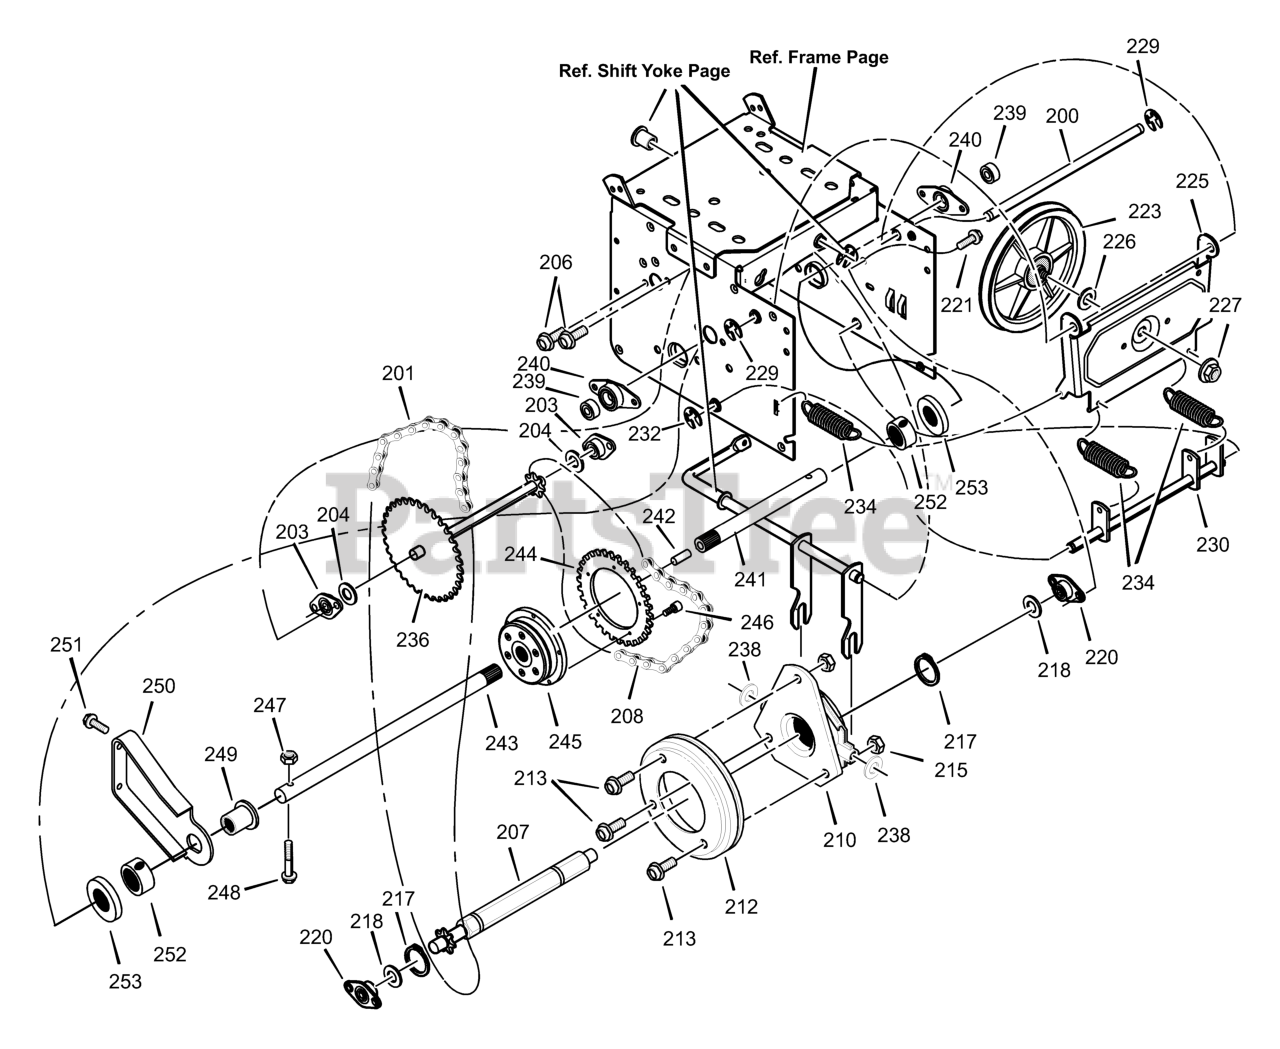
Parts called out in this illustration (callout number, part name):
200	LF AXLE, SWING PLATE YZ
201	CHAIN, ROLLER #420x19.00
203	BEARING AND RETAINER, ASSY
206	SCREW, TAP 5/16-18 x 0.5
207	ASSY, HEX SHAFT
208	CHAIN, ROLLER #420x18.00 LG
210	BEARING, TRUNION CLUTCH R
212	WHEEL, FRICTION DISC
215	NUT, KEPS HEX 1/4-20
217	RING, RETEXT
220	BEARING AND RETAINER, ASSY
221	SCREW, TAP 5/16-18 x .5
223	FRICTION PULLY
225	LF PLATE, SWINGING YZ
226	SPACER, FRICTION PULLEY
227	NUT, FLANGE LOCK 3/8-24
229	RETAINER, RING
230	LF ASSY, SPRING LINK YZ
232	RETAINER, RING
234	SPRING, EXTENSION
236	SET, SPROCKET 33T/7
238	WASHER, FLAT
239	BEARING, BALL
240	RETAINER, BEARING
241	AXLE AND BUSHING, LEFT
242	PIN, AXLE
243	AXLE AND BUSHING, RIGHT
244	SPROCKET
245	CLUTCH, AUTO LOCK
247	NUT
248	BOLT
249	BEARING, AXLE
250	BRACKET, AXLE SUPPORT
251	SCREW
252	COLLAR, LOCKING
